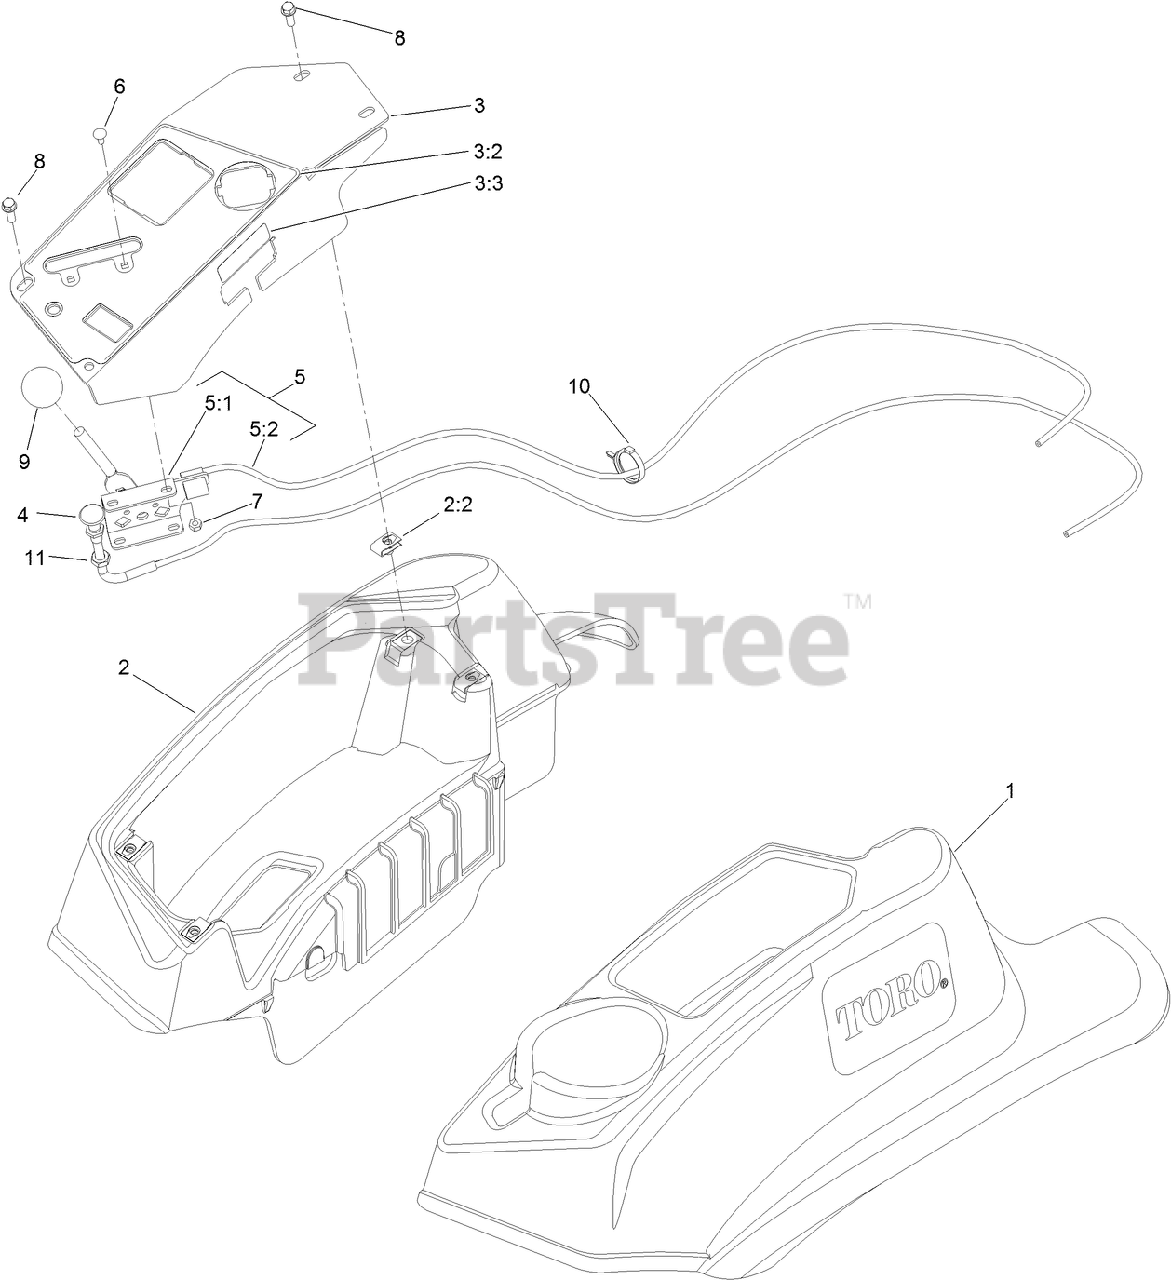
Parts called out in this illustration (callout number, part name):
1	CONSOLE-LH
2	RH CONSOLE ASM
3	CONTROL PANEL ASM
3:2	DECAL-CONTROL PANEL
3:3	DECAL-FUSES
4	CONTROL-CHOKE
5	THROTTLE CONTROL ASM
5:1	LEVER-THROTTLE
5:2	CABLE-THROTTLE
6	BOLT-CARR
7	NUT-LOCK, NI
8	SCREW-HWH
9	KNOB-BALL
10	CLAMP-HARNESS
11	NUT-HJ
